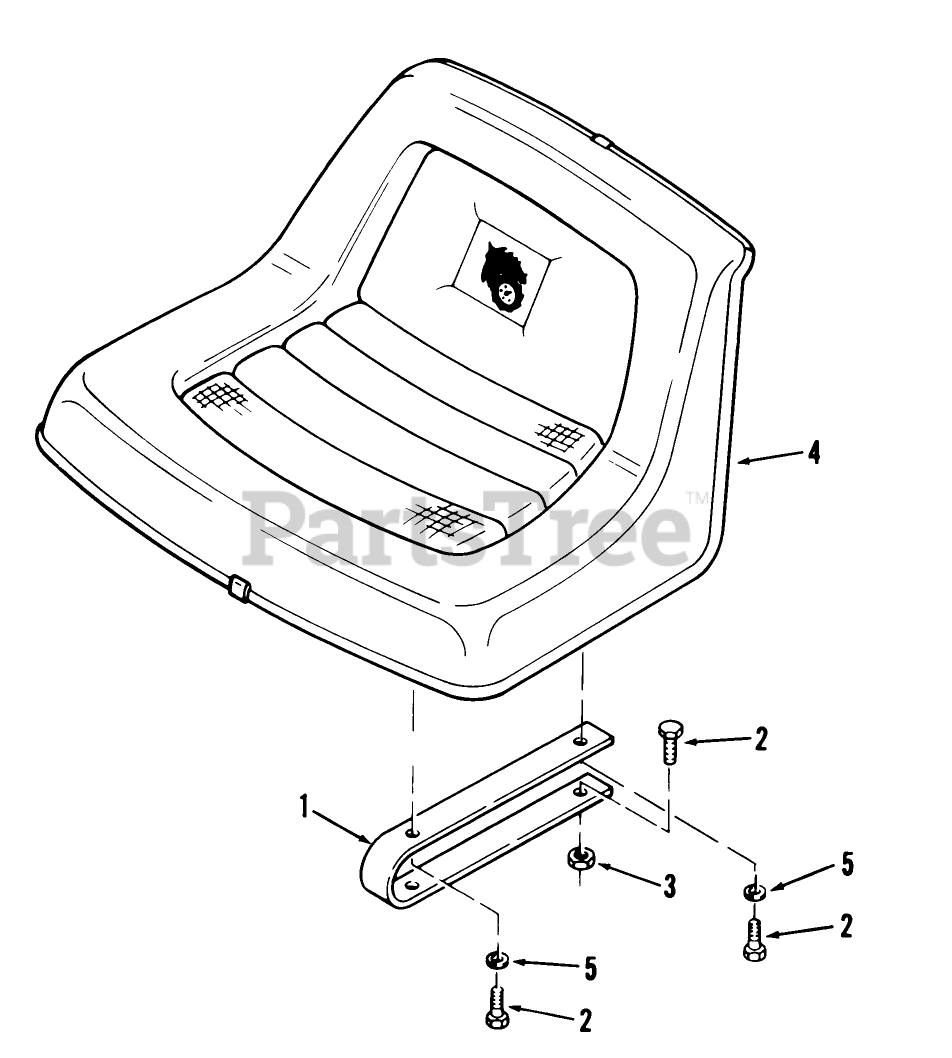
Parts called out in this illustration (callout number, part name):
1	Spring
2	Bolt
3	Nut
4	Seat
5	Lockwasher
